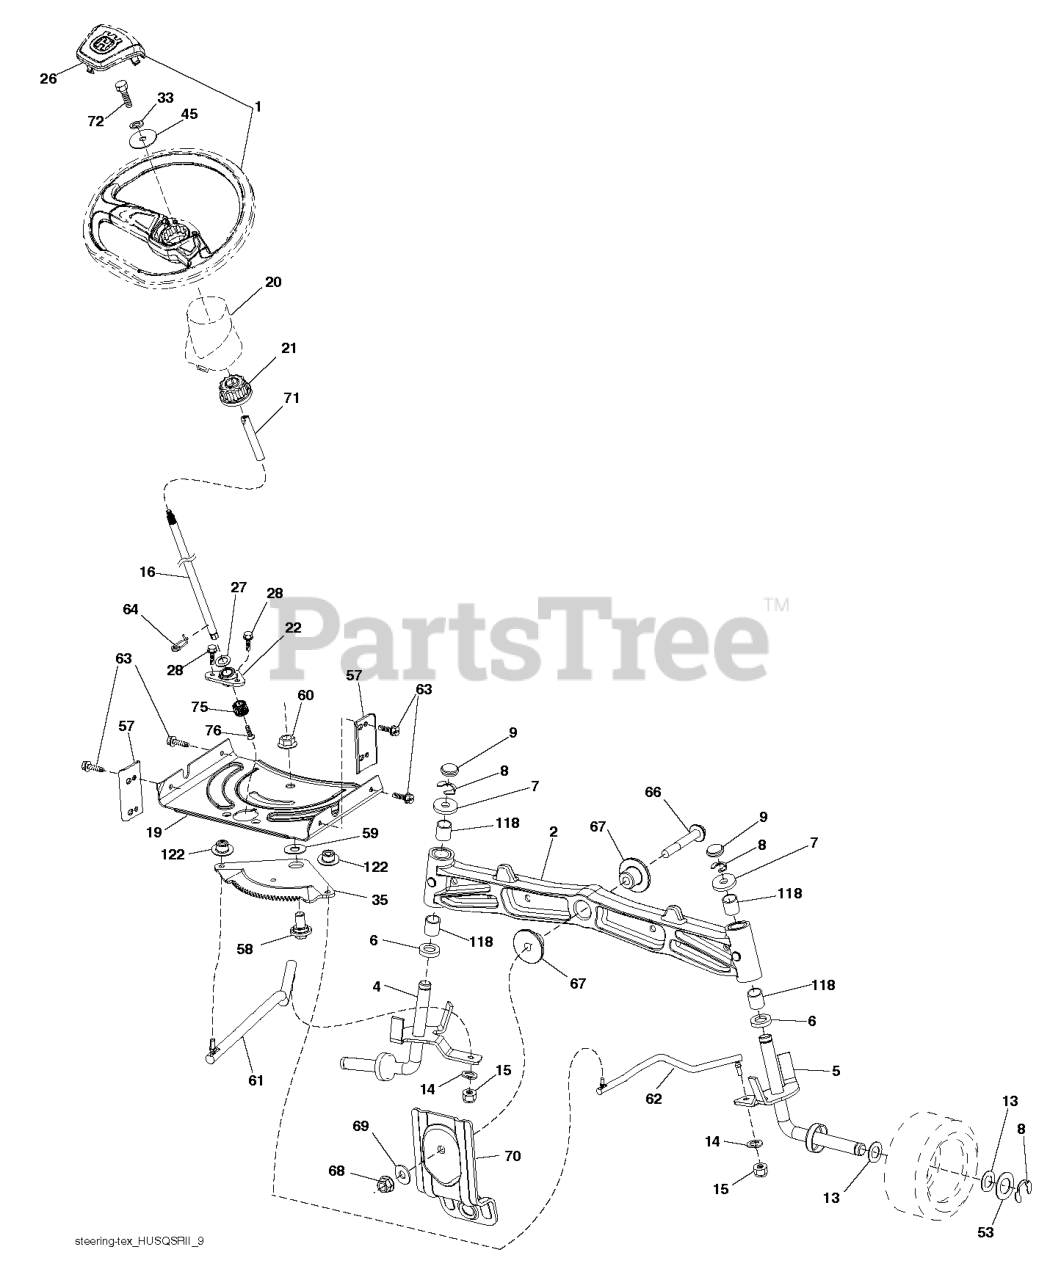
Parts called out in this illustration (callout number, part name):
1	Service Kit
2	AXLE.SVC.ASM CAST IRON.TEX
4	SPINDLE.WELDED.LH.15"TEX
5	SPINDLE.WELDED.RH.15"T
6	WASHER THRUST
9	CAP.SPINDLE.BLACK
15	NUT CROWNLOCK 3/8-24
16	3 HIGH.SHAFT-ZINC.PLATED
19	PLATE.STEER.DDL.NLT/NG
20	STEERING.BOOT.HUSQ.LT
21	ADAPTER, WHEEL STNG..
22	BEARING.SHAFT.STEER.LOWER.625
28	SCREW, 3/8-16X3/4
33	WASHER.LOCK.HVY.HLCL.SPR.5/16
35	GEAR.SECTOR.PLATE.DDL.
53	WASHER.HARDENED
57	BRACKET.UPSTOP.TEX
58	BOLT.SHOULDER.SECTOR.P
59	WASHER.THURST.SECTOR.S
60	NUT FLANGE LOCK 5/8-11
63	SCREW
64	RETAINER.CLIP.SPRING.S
66	BOLT HEX FGHD 7/16-14 X 3 SERR
67	BUSHING.PM.FRONT AXLE
68	NUT.LOCK.FLANGE.7/16
69	WASHER.1.5X.505X.118
70	BRACKET.FRT.DECK.SUSP.RR.MT431
71	SHAFT.EXTEN.STRG.SPLINE
75	PINION.ZINC PLATED
76	SCREW HEAD SOCKET LRVB
118	BUSHING, AXLE CAST
122	CAP.GEAR.SECTOR.TEX
